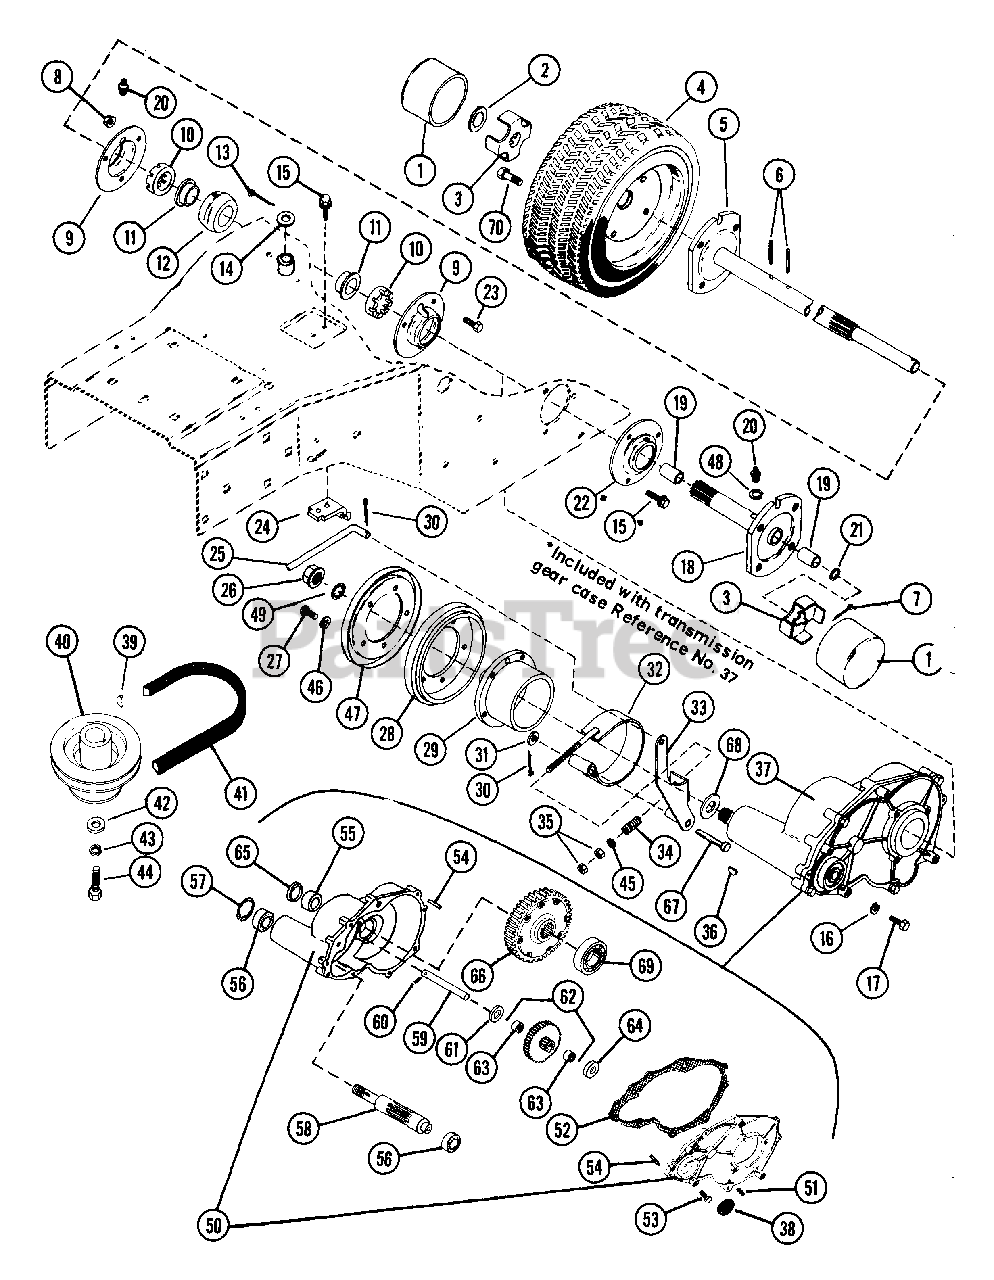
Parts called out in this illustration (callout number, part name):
1	HUB CAP
2	PUSHNUT
3	SPINDLE CUP
4	TERRA TIRE & WHEEL ASSEMBLY
5	R H AXLE SHAFT
6	PIN-ROLL .188X1.50
7	PIN-COTR .12 X 1.25 PL
8	NUT-LK-FLG .250-20 PL
9	BEARING FLANGE
10	ADJUSTMENT SPACER
11	BSHG-FLG 1.125X1.31X.50X1.62BR
12	SPHERICAL BUSHING
13	PIN-COTR .12X1.0 PL
14	WSHR-FL-STL .505X.880X.072 PL
15	BLT-SCRHFWH .25-20X.62 PL
16	WSHR-LK .312X.097 PL HVY
17	BLT-HEX .31-18X1.50 PL GR2
18	L H AXLE ASSEMBLY
19	BSHG-SLV .750X.814X .750 BRZ
20	SPIN DRIVE ZERK FITTING
21	O-RING .755X.950X.097
22	SEAL 1.125X2.496X.380
23	BLT-HEX .25-20X.50 PL GR2
24	NEUTRAL STOP
25	BRAKE ROD
26	NUT-LK-NYL.625-18 PL
27	BLT-HEX .31-18X.50 PL GR2
28	FRICTION DISC
29	FRICTION DISC HUB
30	PIN-COTR .09X.75 PL
31	WSHR-FL-STL .380X.626X.033
32	BRAKE BAND
33	BRAKE LEVER
34	SG-COMP .105X.585X.75
35	NUT-HEX .312-18
36	KEY-WDRF .188X.875X.375 SAE11
37	GEAR CASE ASSEMBLY
39	KEY-STR .25X2.0X.25
40	ENGINE SHEAVE
41	V-BELT, SAE 380-RAW EDGE
42	WSHR-FL-STL .438X1.125X.19
43	WSHR-LK .375X.115 HVY PL
44	BLT-HEX .38-24X1.25 BLKO GR5
45	WSHR-FL-STL .323X.625X.062 PL
46	WSHR-LK-INT .313X.030 PL
48	WSHR-LK .250X.047 LT PL
49	WSHR-LK-INT .625X.045 PL
50	COVER & CASE ASSEMBLY
51	BREATHER
53	SCR-FLG-WHZ 10-24X.75 PL
54	PIN-GRV .188X.63
55	BSHG-SLV 1.125X1.375X.625
56	BRG-BALL .625X1.375X.44
57	RG-RTNG-INT 1.375X.050
58	PINION SHAFT
59	IDLER SHAFT
60	PIN-ROLL .125X.75
61	WSHR-FL-STL .505X1.000X.062
62	PINION & GEAR W/BEARING ASSEMB
63	BRG-NEEDLE .50X.688X.625
64	SPACER .507X.875X.289
65	SEAL 1.125X1.624X.250
66	DIFFERENTIAL ASSEMBLY
67	CLEVIS PIN
68	WSHR-FL-STL .627X.990X.032
69	BRG-BALL 1.125X2.50X.63
70	BLT-WHL .50-20X.75 GR5 PL
